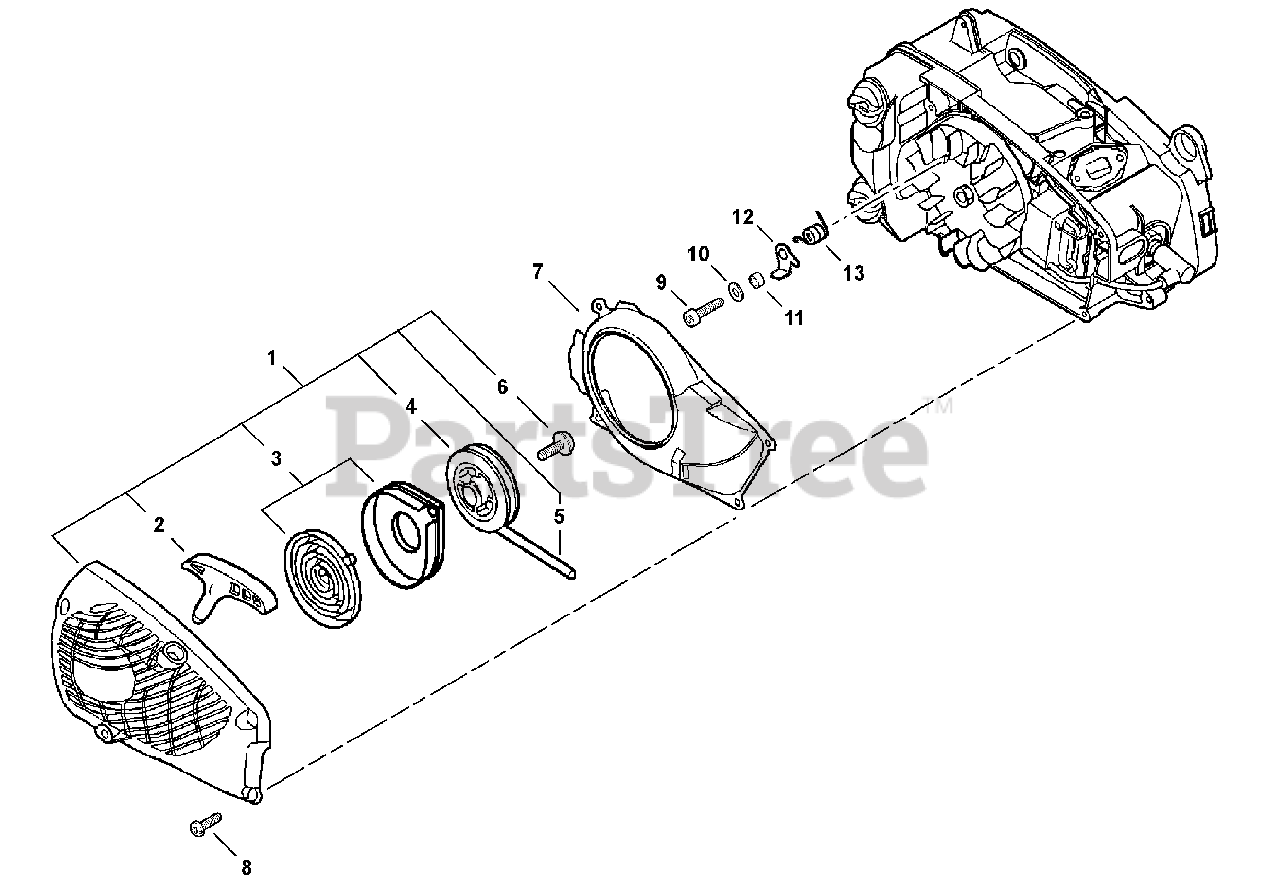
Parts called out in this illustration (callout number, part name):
1	STARTER ASSY
2	GRIP, STARTER
3	REWIND SPRING ASSY
4	REEL, ROPE
5	ROPE, STARTER - 3X920
7	COVER, FAN
9	SCREW - 5X14
10	WASHER - 5
12	PAWL, STARTER
13	SPRING, RETURN
